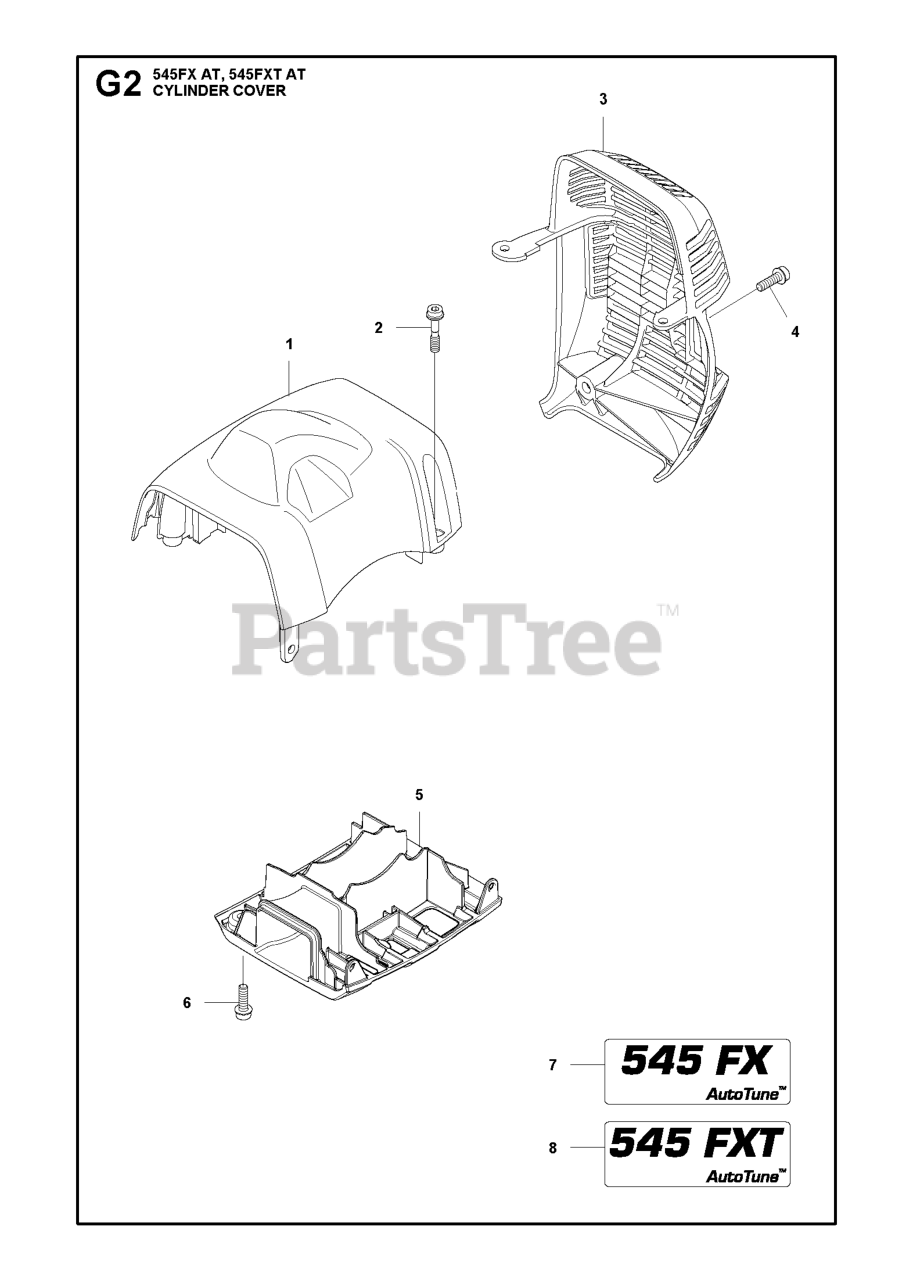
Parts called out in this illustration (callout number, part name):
1	CYLINDER COVER
2	SCREW IHSCFMO
3	HEAT PROTECTOR
4	SCREW IHSCFM
5	SKID PLATE ASSY
6	SCREW IHSCFM
7	LABEL CYLINDER COVER FX
8	LABEL CYLINDER COVER FXT
